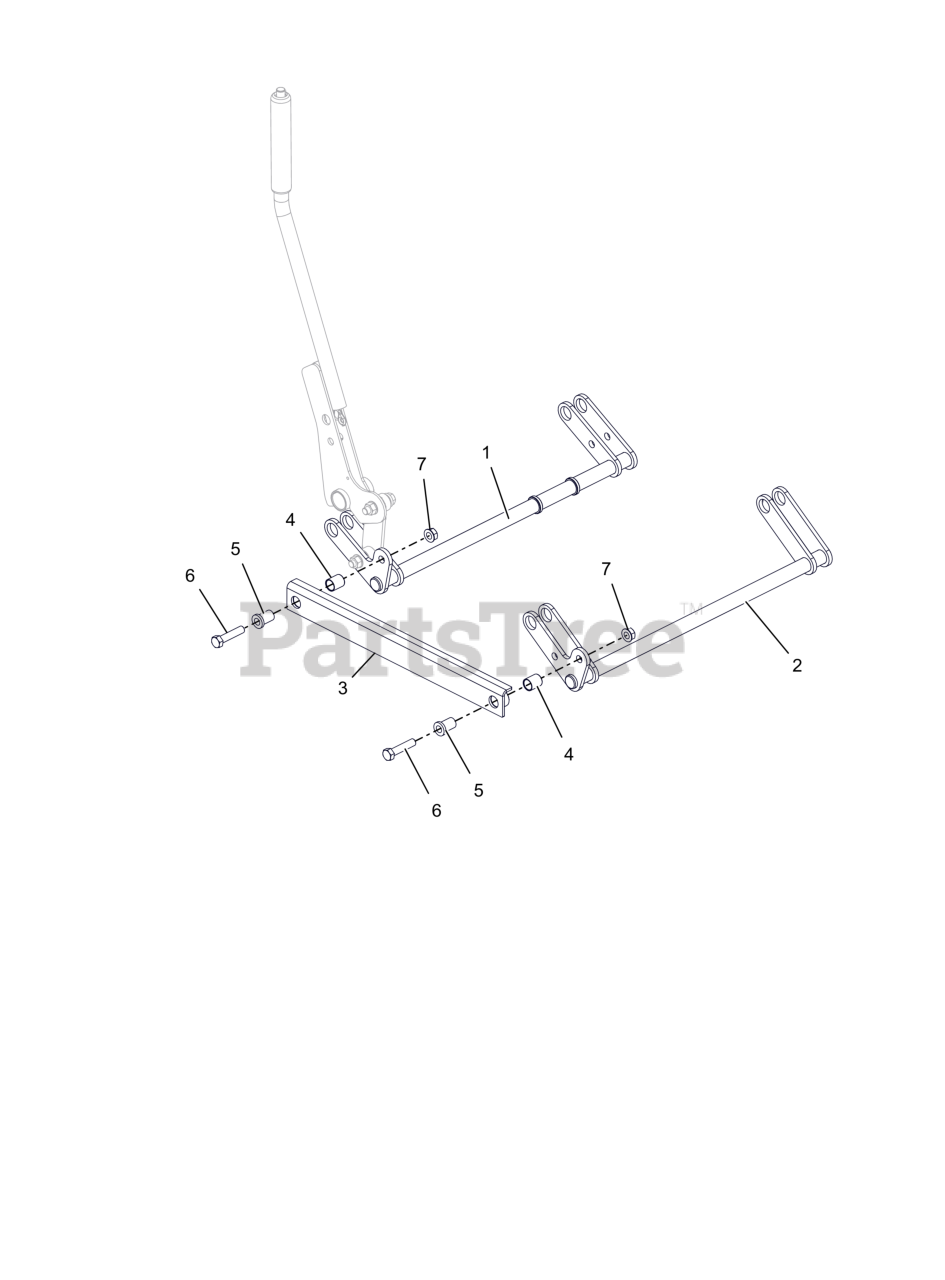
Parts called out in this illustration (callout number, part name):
1	WLDMT, 36" PROSTANCE DECK LIFT (BLACK)
2	WLDMT, 36" PROSTANCE DECK LIFT
3	LINK, 36" DECK LIFT
4	BRG, .750 X .875 X 1.000
5	BSHG-FLG .515X.746X1.290X1.000
6	BLT, HEX .50-13X2.25 G5 ZCC
7	NUT-LK-CTR-FLG .500-13 GG ZCC
